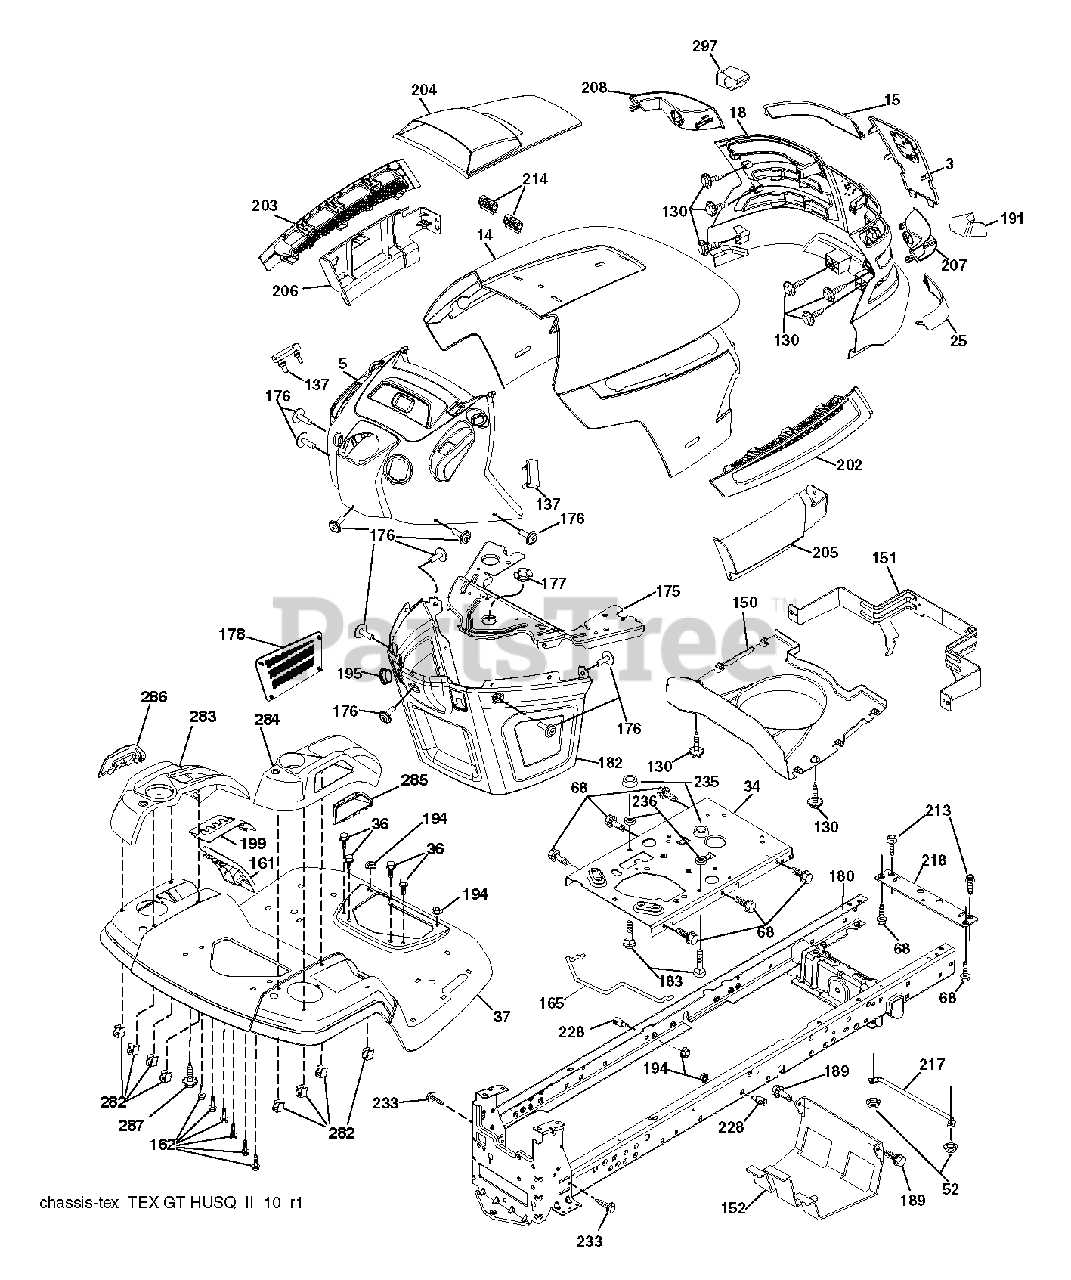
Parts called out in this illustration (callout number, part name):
3	APPLIQUE.SUBASM.GT.HUSQ.II
5	DASH.UPR.ASSY.GT2.SRVMNDER.PTO
14	HOOD.ASM.HUSQVARNA.GT.TEX.ORAN
15	LENS.HEADLIGHT.LH.GTII.2011
18	GRILLE.SUBSTRATE.2011.
25	LENS.HEADLIGHT.RH.GTII.2011
34	PLATE.ENGINE.WELDED.CHASSIS
36	SCREW 5/16"
37	FENDER.TLT.FS.W/CPH/FW/RSF.668
52	LOCKNUT
68	SCREW LT
130	SCREW.#10 X 0.750.BOS
137	BUMPER DASH
150	AIR.DUCT.GTV.BLACK
151	BRACKET.PIVOT.HOOD.GT.HUSQ.II
152	SHIELD.BROWNING.W/TEX
161	WINDOW.FUEL.LT.HUSQ.TEX.498
162	SCREW.HI-LO.CONSOLE
165	SUPPORT.TANK.REAR.W/TEX
175	PLATE.CROSSMEMBER.HUSQ
176	SCREW.#10-24X5/8.RN.QU
177	BUSHING, STEERING
178	CARGO.ASM.NET.TXGT.W/C
180	CHASSIS
182	DASH.LOWER.COMMON.12V.ADAPTOR
183	BOLT.5/16-18X1-1/4 FULL THD
189	SCREW
191	INSERT.REFLECTIVE.RH.HUSQ.GTII
194	NUT LOCK HEX FLANGE 5/16-18
195	PLUG.HOLE.DASH.LOWER.12V.BLK
199	PLATE.DECK.LIFT.HUSQ.LT
202	VENT.SIDE.RH.GT.HUSQ.II.
203	VENT.SIDE.LH.GT.HUSQ.II.498
204	VENT.TOP.HUSQ.GT2
205	SIDE.TRIM.RH.GT.HUSQ.II
206	SIDE.TRIM.LH.GT.HUSQ.II.GRAY
207	BEZEL LIGHT.RH.GT.II.MYLAR
208	BEZEL LIGHT.LH.GT.II.MYLAR
213	BOLT
214	CLIP.RETAINER.TINNER.
217	ROD.PIVOT.HOOD
218	X-PIECE.HOOD.STOP.NON/
228	STUD.FASTNER.W/ANTI-ROTATE
233	BOLT.SHOULDER
235	SPACER FENDER
236	NUT.CENTERLOCK.5/16-
282	CLIP.RETAINER.CONSOLE.LT.HUSQ
283	CONSOLE.ASM.LFT.RSF.HUSQ.LT
284	CONSOLE.SHFT.PDL.CNTRL.HUSQ.LT
285	CONSOLE INSERT RH
286	CONSOLE.INSRT.LH.HUSQ.LT.BLACK
287	SCREW 1/4X20
297	INSERT.REFLECTIVE.LH.HUSQ.GTII
